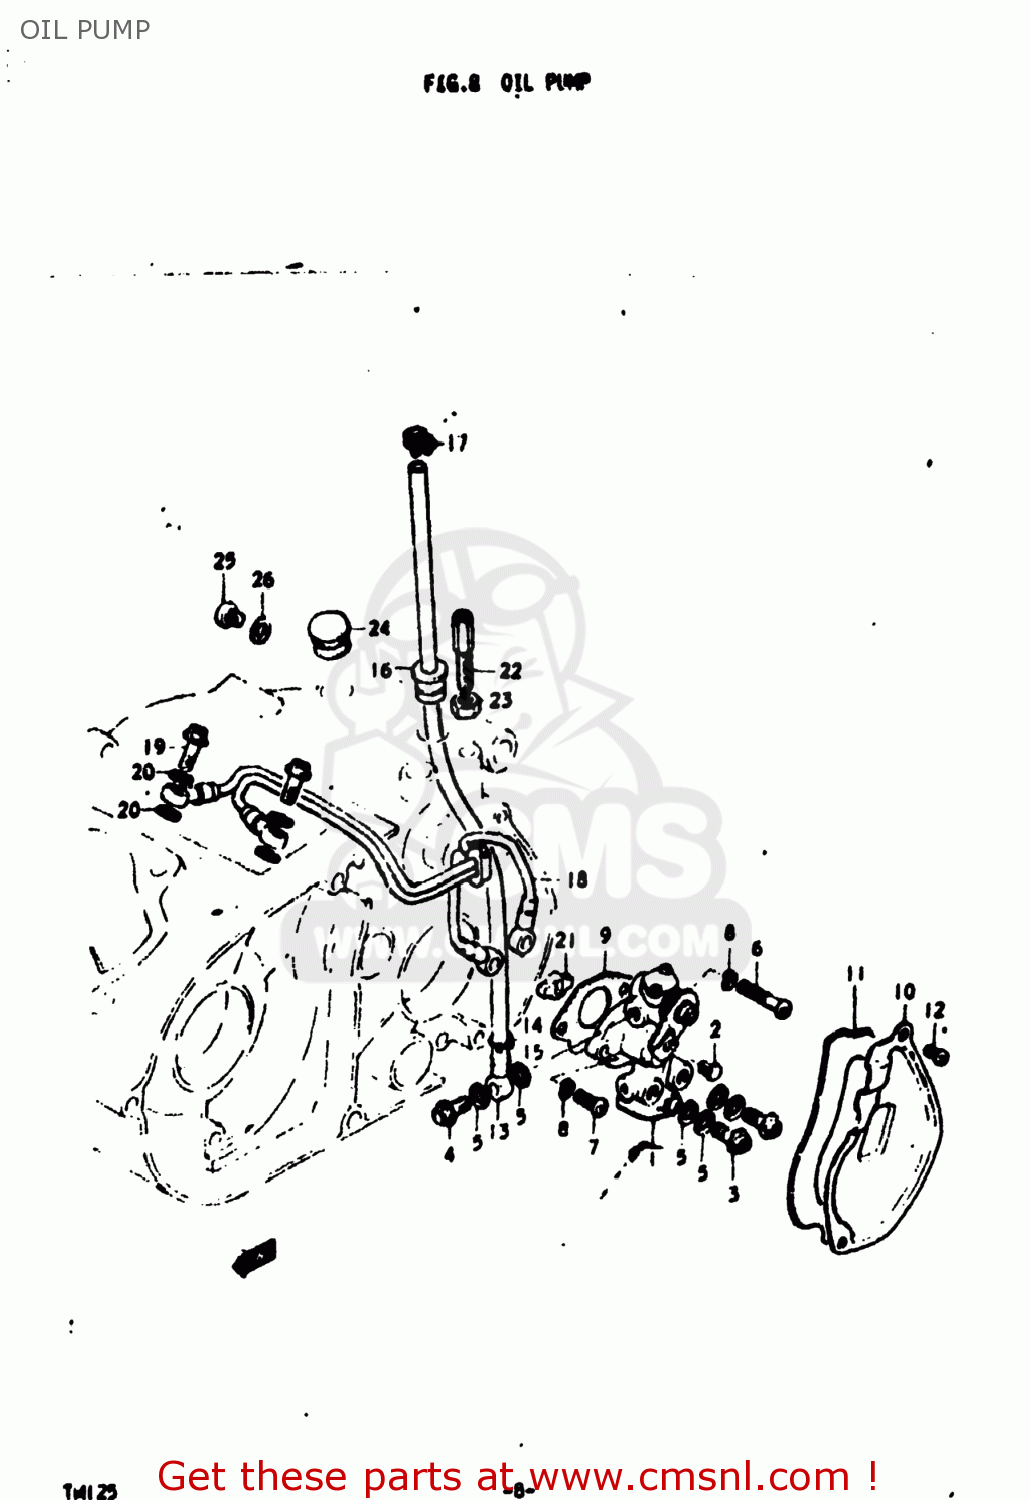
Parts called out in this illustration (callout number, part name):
1	PUMP ASSEMBLY,OIL
2	TERMINAL,CABLE
3	UNION BOLT
4	UNION BOLT
5	GASKET (NAS)
6	SCREW
7	SCREW
8	LOCK WASHER
9	GASKET,OIL PUMP (MCA)
10	CAP,OIL PUMP INSPECTION
11	GASKET,OIL PUMP INSPECTION (NAS)
12	SCREW
13	HOSE,OIL NO.1
14	CLIP
15	CLIP
16	BUSHING
17	CLAMP
18	HOSE,OIL NO.2
19	UNION BOLT
20	GASKET
21	PIECE,OIL PUMP DRIVE
22	BOLT
23	NUT
24	Plug
25	SCREW,6X6
26	WASHER
